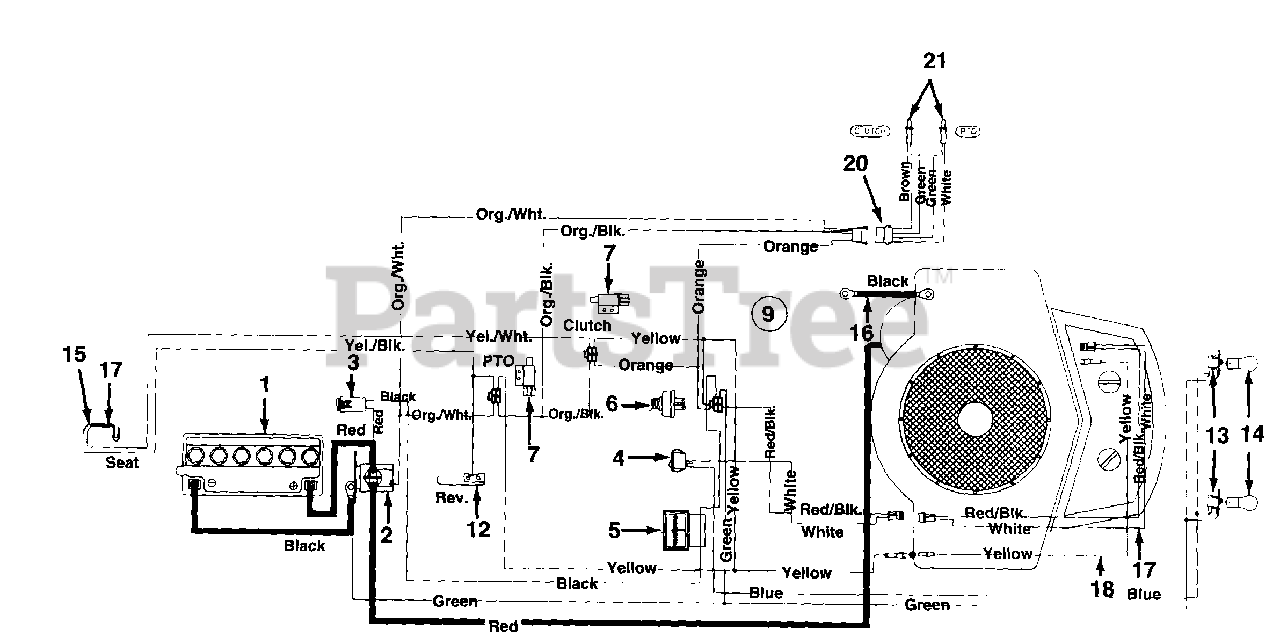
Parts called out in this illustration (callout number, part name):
1	Battery
2	Solenoid
3	Fuse 7.5 Amps
4	Light Switch
5	Ammeter
6	Ignition Switch
7	Safety Switch
9	Wire Harness
12	Safety Switch (Reverse)
13	Socket
14	Bulb (Headlight)
15	Safety Switch (Seat)
16	Ground Wire 7.5" Lg.
17	Safety Switch (Seat)
18	Harness Adapter
20	Monitor Harness
21	Monitor Bulb
